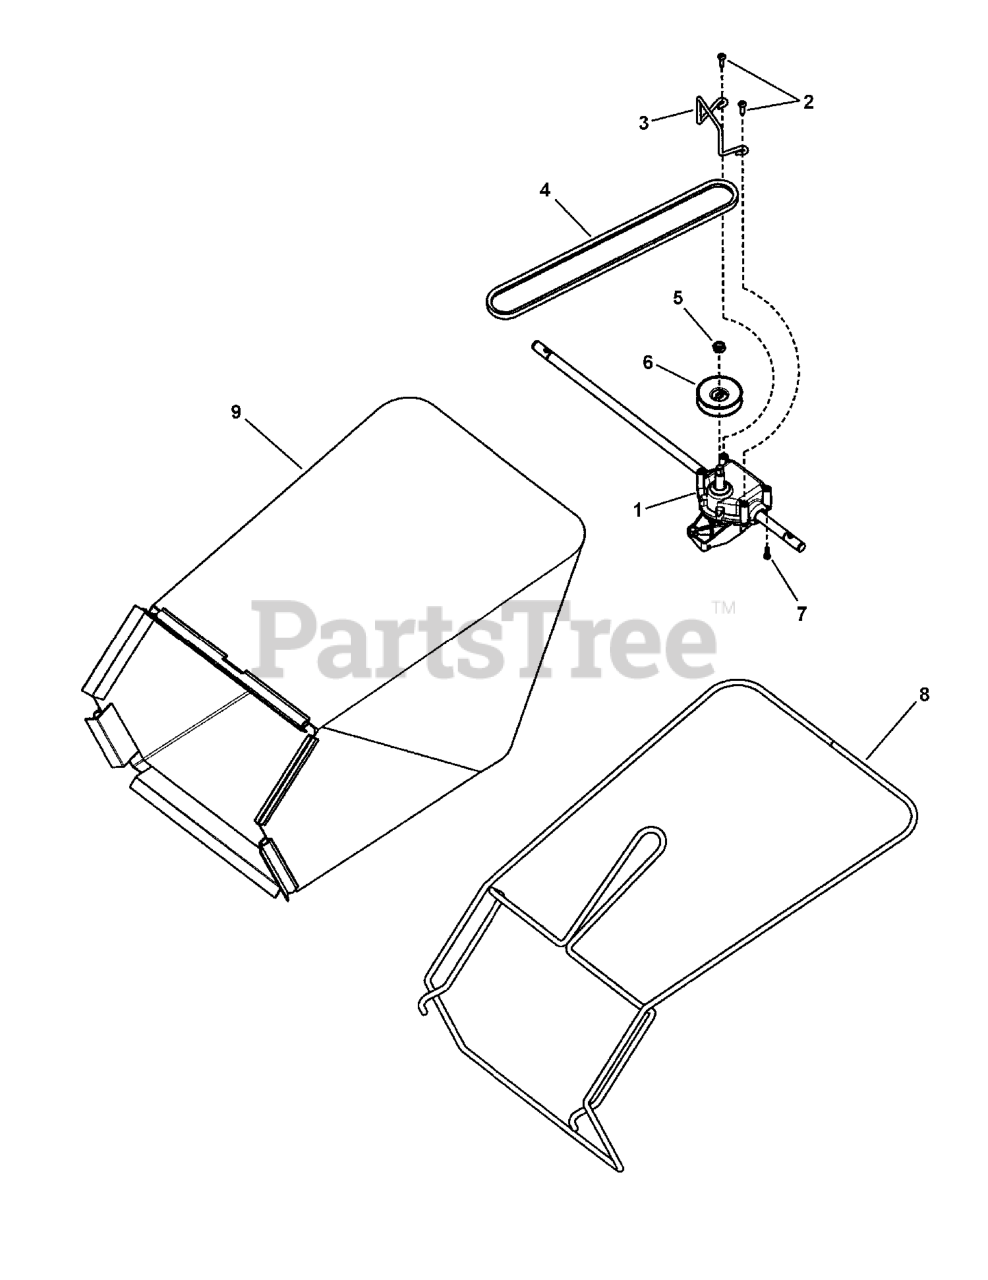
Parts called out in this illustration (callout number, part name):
1	TRANSMISSION, VS, RWD
2	SCREW, #10-16 x 3/4" Pan Head Self-Tap, Combo
3	BELT GUIDE, Transmission, 22" WBM
4	BELT, 3L, 33.83" Effective Length
5	NUT, 3/8-16 Hex Center Lock Jam
6	PULLEY, Trans VAR SPD LC WBM
7	SCREW, 7mm x 1 x .550 AB Point
8	BAG FRAME, RD, 22" WBM
9	GRASS BAG, 22" Rear Discharge
